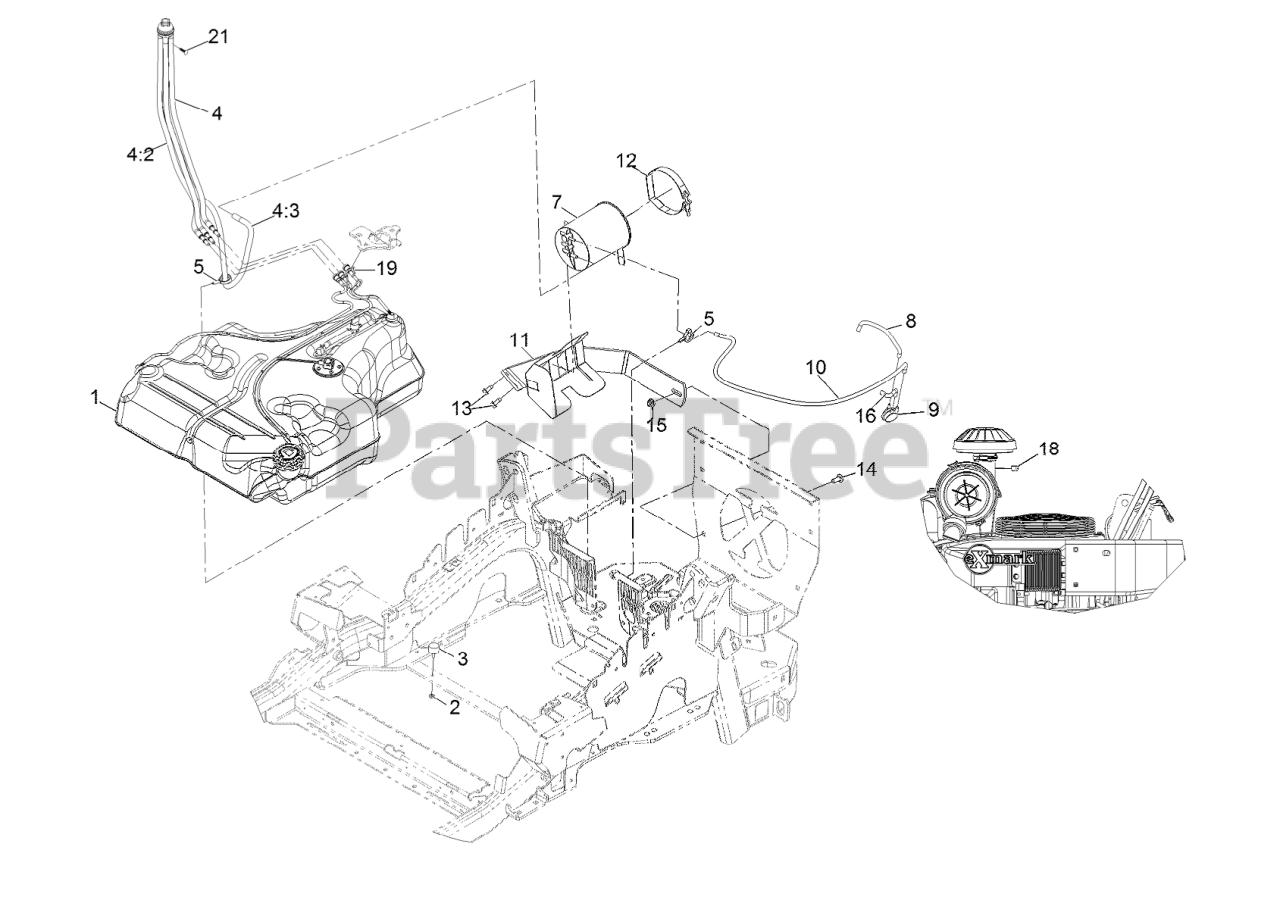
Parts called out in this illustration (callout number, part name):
1	ASM-8 GALLON FUEL TANK
2	NUT-JAM
4	FUEL MANIFOLD VENT ASM
4:2	HOSE-FUEL
4:3	HOSE-FUEL
5	CLAMP-HOSE
7	CANISTER-CARBON, 1200CC
8	BRACKET-VALVE MOUNT
10	GROMMET
11	MOUNT-CANISTER
12	CLAMP, T-BOLT
13	Screw-HWH 5/16-18 X 3/4 Tf
14	SCREW-CARR
15	NUT-HF, NI
16	TIE-PLASTIC
17	SCREW-HHF
18	PLUG-PORT
19	RETAINER-LINE, VAPOR
21	PLUG-PLASTIC
22	WASHER-SPRING
23	HOSE-FUEL
24	HOSE-FUEL
25	Hose-Fuel
26	FITTING-STRAIGHT
